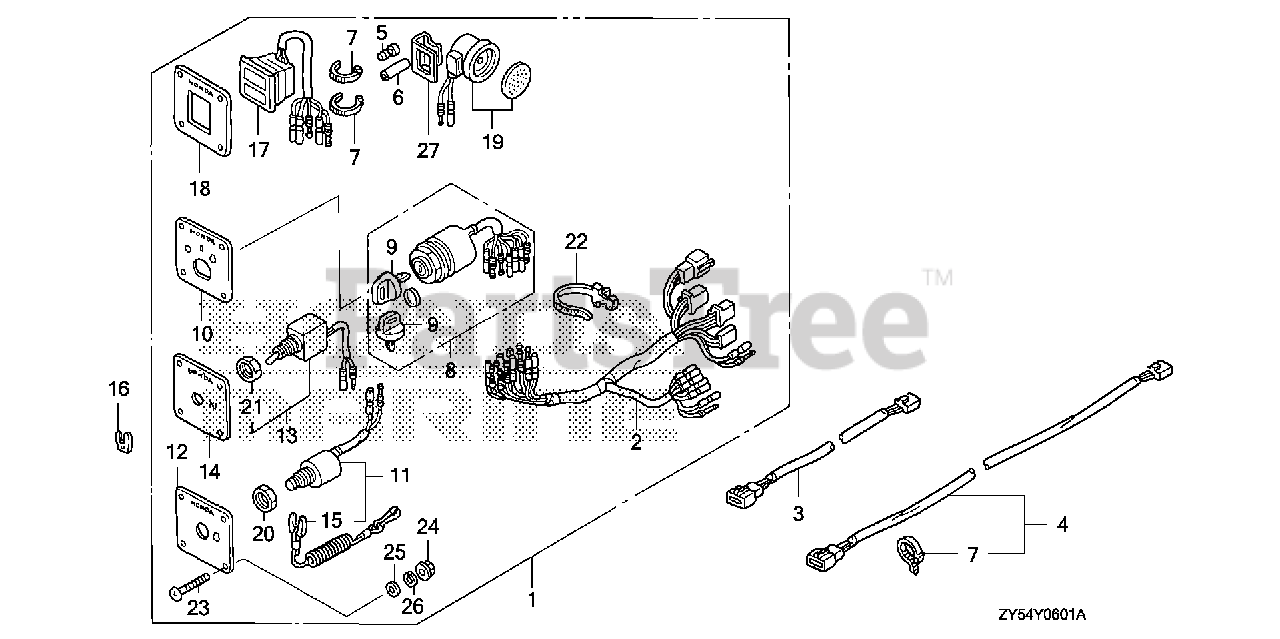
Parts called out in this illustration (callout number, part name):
1	PANEL KIT, CONTROL (2-LED) (A)
2	HARNESS ASSY., SWITCH PANEL
3	CABLE ASSY., EXTENSION (3P 7FT) (FOR 2-LED)
4	CABLE ASSY., EXTENSION (3P 30FT) (FOR 2-LED)
5	PLUG, CONNECTOR (INNER) (TROLLING CONTROL)
6	PLUG, CONNECTOR (OUTER) (ENGINE NO.)
7	TIE, CABLE (NATURAL 2.4X92) Use up to Frame SN 1300359.
8	SWITCH ASSY., COMBINATION DUAL QTY = (2) (SINGLE)
8	SWITCH ASSY., COMBINATION (SINGLE) (DUAL)
9	KEY ASSY., COMBINATION SWITCH (35100-ZV5-003 ONLY) DUAL QTY = (4) (SINGLE)
10	PANEL, SWITCH
11	SWITCH ASSY., EMERGENCY STOP
12	PANEL, EMERGENCY STOP SWITCH
13	SWITCH ASSY., SOLENOID
14	PANEL, SOLENOID
15	WIRE, EMERGENCY (SINGLE) (DUAL)
16	CLIP, EMERGENCY LOCK
17	LAMP ASSY., INDICATOR (2-LED)
18	PANEL, INDICATOR
19	BUZZER, WARNING
20	NUT, HEX. (16MM) DUAL QTY = (2) (SINGLE)
21	NUT, HEX. (12MM)
22	BAND, WIRE HARNESS (150MM) (NATURAL) DUAL QTY = (2) (SINGLE)
23	SCREW, PAN (5X40) DUAL QTY = (8) (SINGLE)
24	NUT, FLANGE (5MM) DUAL QTY = (8) (SINGLE)
25	WASHER, PLAIN (5MM) DUAL QTY = (8) (SINGLE)
26	WASHER, SPRING (5MM) DUAL QTY = (8) (SINGLE)
27	BRACKET, BUZZER
